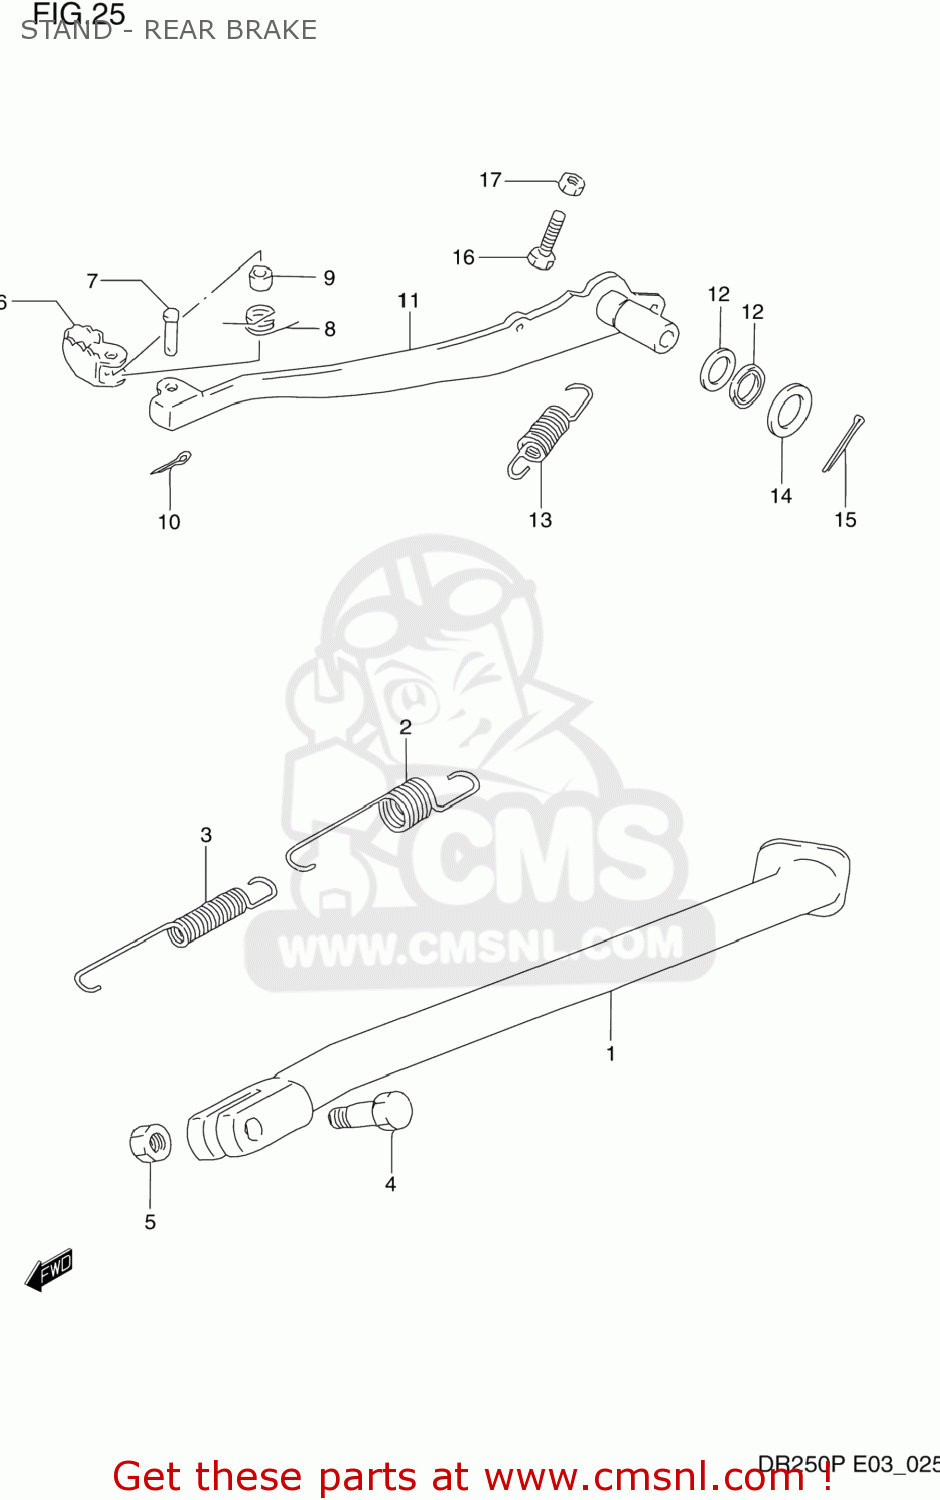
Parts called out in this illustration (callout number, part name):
1	STAND,SIDE
2	SPRING
3	SPRING
4	BOLT(10X30)
5	NUT
6	PEDAL,BRAKE
7	PIN
8	SPRING
9	SPACER(9.2X9X6.5)
10	PIN
11	ARM,BRAKE PEDAL
12	SEAL,OIL(15X21X3)
13	SPRING
14	WASHER(15.5X26X2.3)
15	COTTER PIN
16	BOLT(6X23)
17	NUT 6MM
